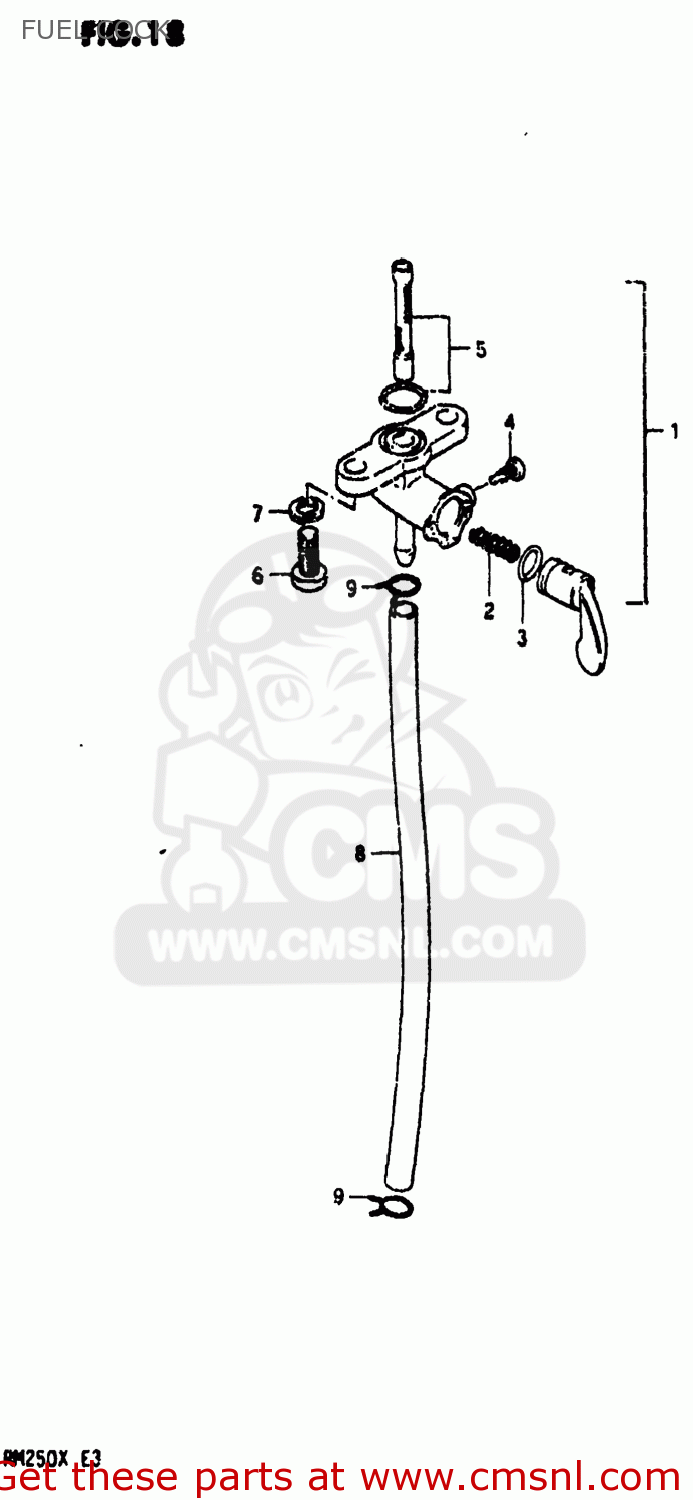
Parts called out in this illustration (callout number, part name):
1	COCK ASSEMBLY,FUEL
2	SPRING,FUEL COCK VALUE
3	O RING,LEVER
4	SCREW
5	FILTER SET FUEL
6	SCREW
7	LOCK WASHER
8	HOSE
9	CLIP
